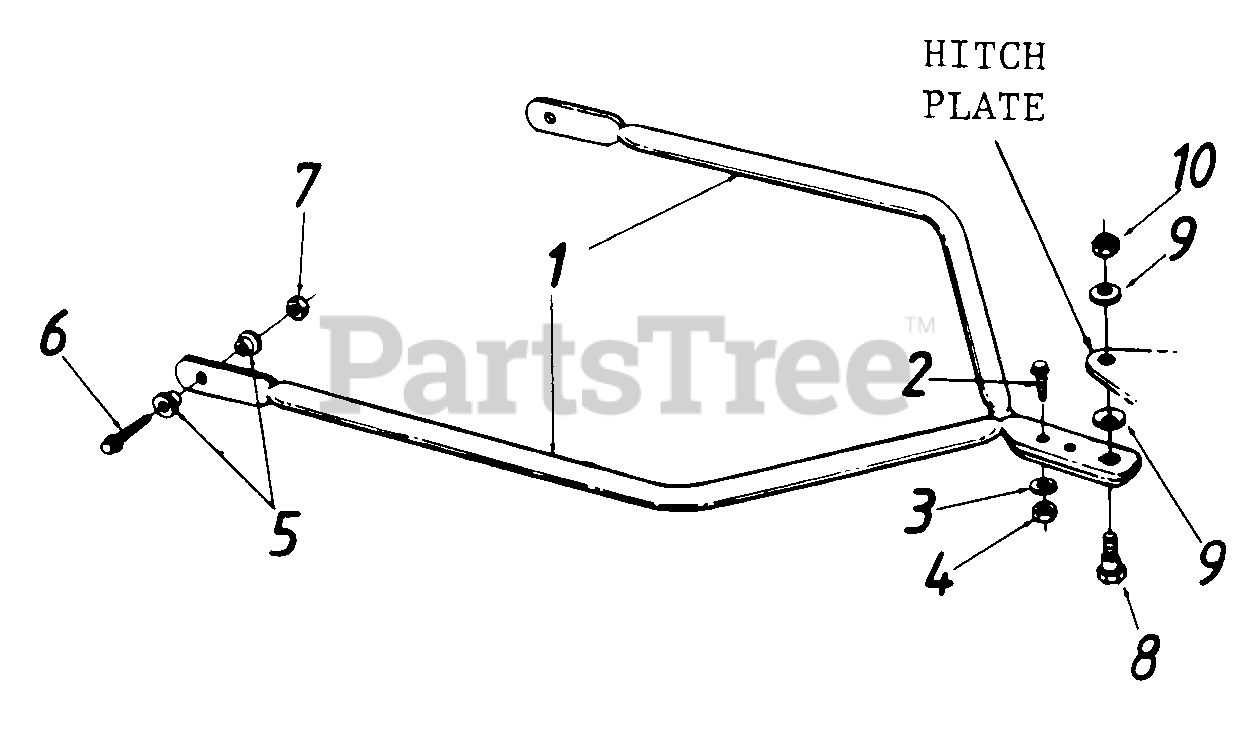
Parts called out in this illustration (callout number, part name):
3	L.-Wash. 1/4" I.D.
4	Hex Nut 1/4-20 Thd.
5	Shoulder Spacer
6	Hex Wash. Hd. Self-Tapp Scr. 5/16-18 x 1.0" Lg.
7	Hex Nut 5/16-18 Thd.
8	Shoulder Bolt
9	Bell-Wash. .39" I.D. x 1.12"
10	Hex Top Jam Nut 3/8-16 Thd.
